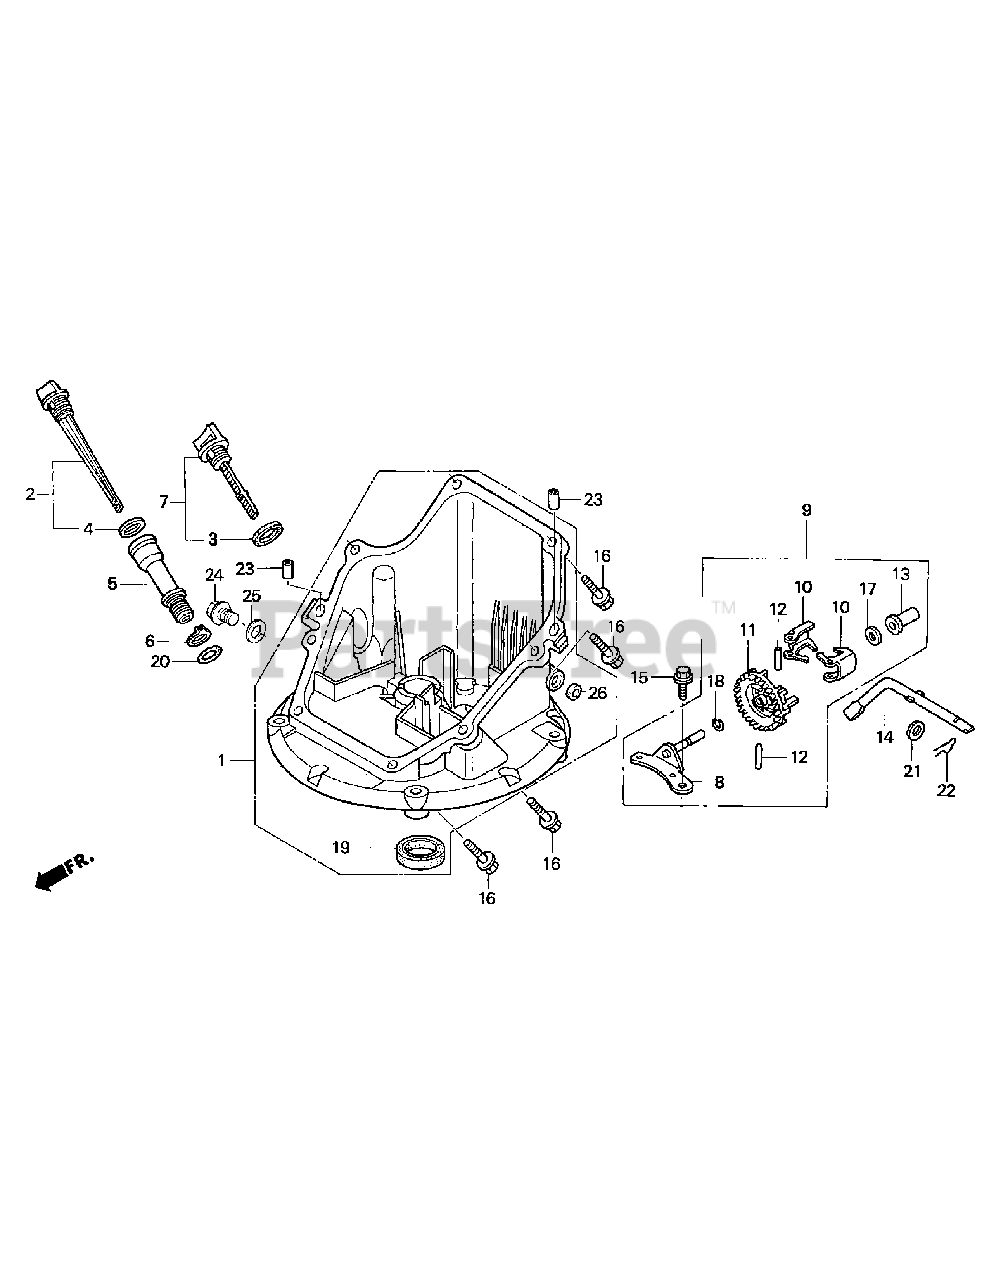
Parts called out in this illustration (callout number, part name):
1	PAN ASSY., OIL (SAE)
3	GASKET, OIL FILLER CAP
7	GAUGE ASSY., OIL LEVEL
8	SHAFT, GOVERNOR HOLDER
9	GOVERNOR ASSY.
10	WEIGHT, GOVERNOR
11	HOLDER, GOVERNOR WEIGHT
12	PIN, GOVERNOR WEIGHT
13	SLIDER, GOVERNOR
14	SHAFT, GOVERNOR ARM
15	BOLT, FLANGE (6X14)
16	BOLT, FLANGE (6X25)
17	WASHER, THRUST (6MM)
18	CLIP, GOVERNOR HOLDER
19	OIL SEAL (28X41.25X6)
21	WASHER, PLAIN (6MM)
22	PIN, LOCK (8MM)
23	PIN, DOWEL (8X20)
24	BOLT,DRAIN PLUG
25	WASHER, DRAIN PLUG (12MM)
